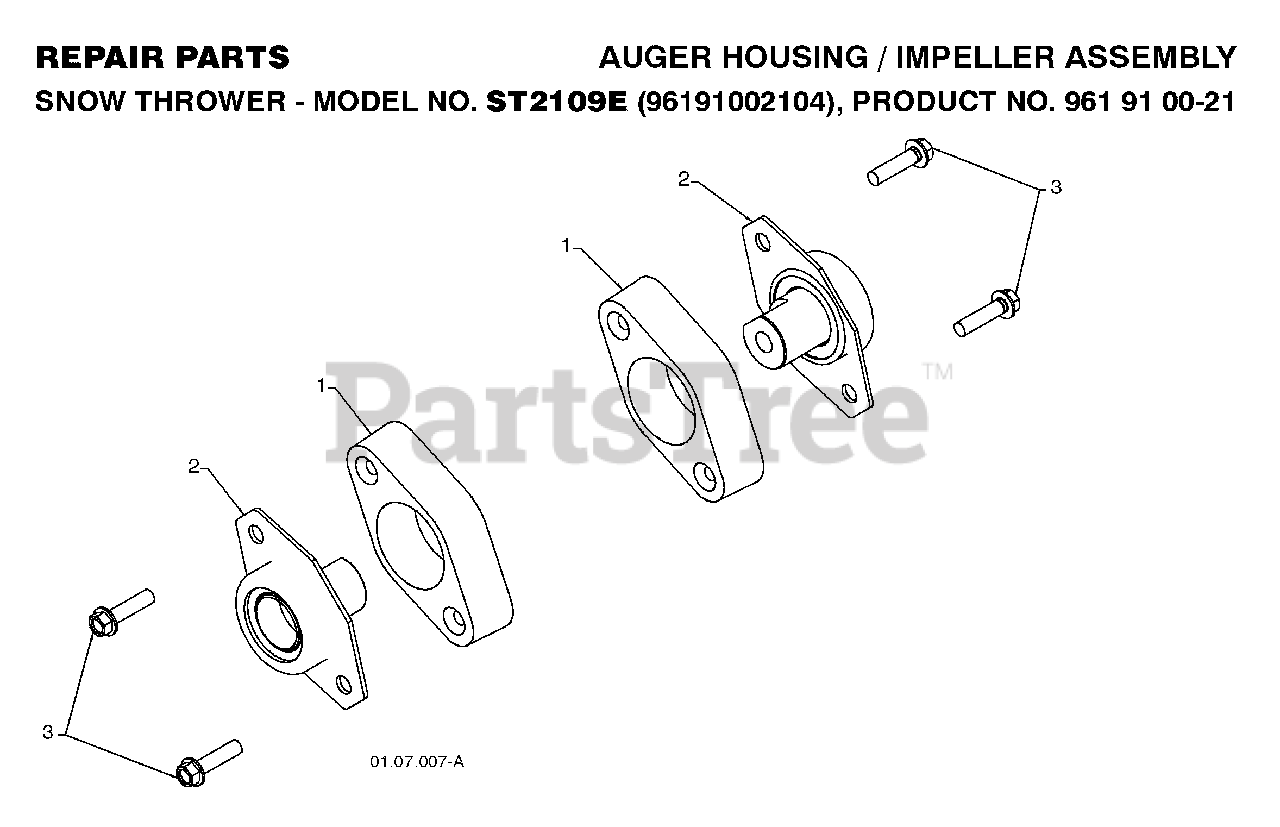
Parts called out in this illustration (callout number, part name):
1	BEARING RETAINER, PLASTIC
2	BEARING.BALL.AUGER
3	SCREW, HEX HD 5/16X1
